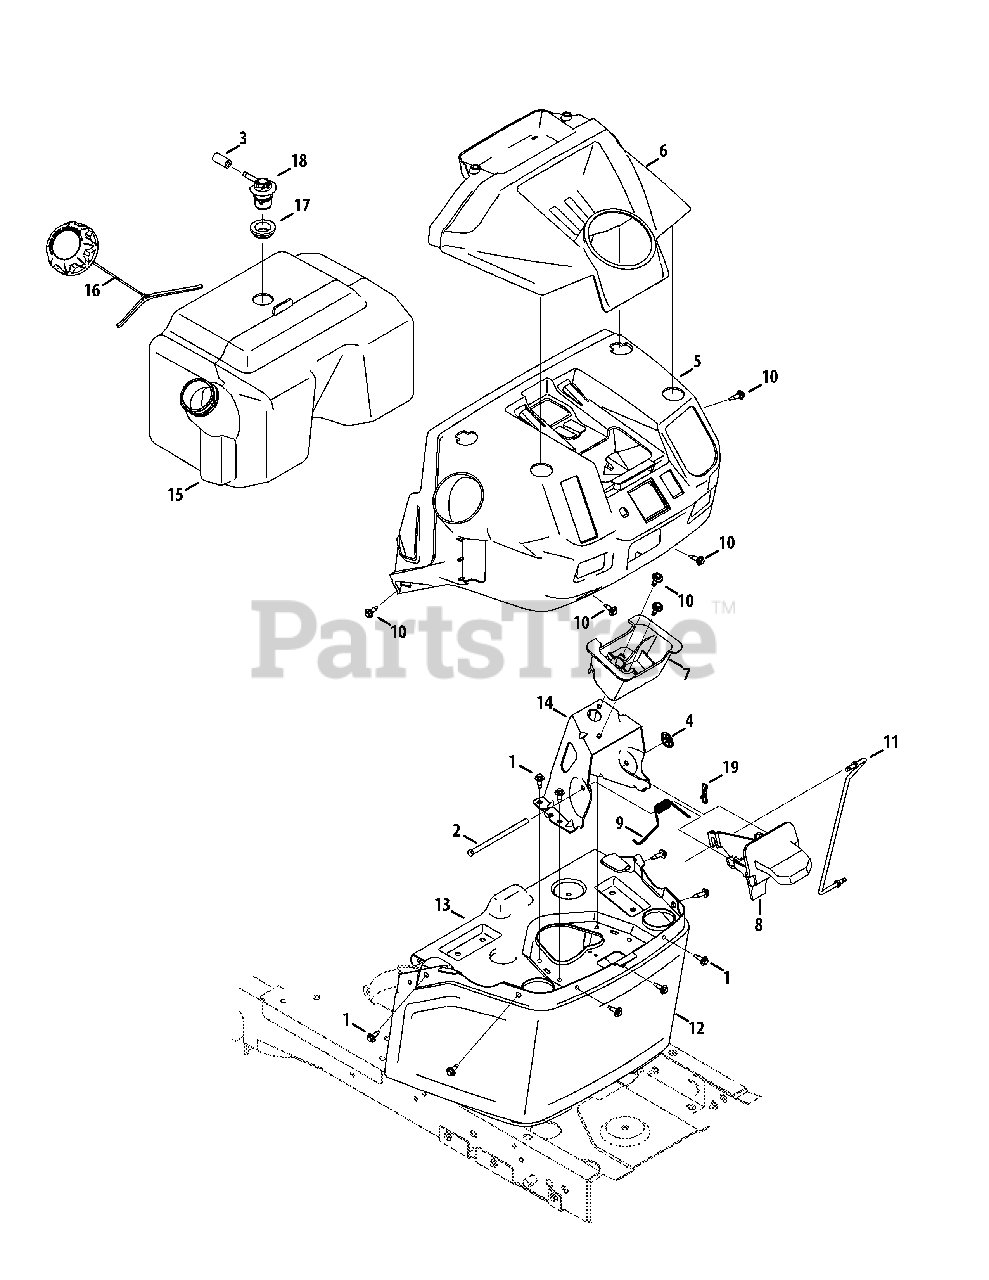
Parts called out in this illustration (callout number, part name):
1	Screw, M6-1 x .625
2	Hinge Pin, .25 Dia x 4.50 LG
3	Hose, Vent (Kohler Courage Single)
4	Push Nut, .25 Dia.
5	Upper Dash
6	Dash Cap
7	Steering Shaft Bearing
8	Dash Lever
9	Torsion Spring, .330 ID
10	Shoulder Screw, .368 x .115, M6-1
11	Control Rod
12	Lower Dash
13	Dash Plate
14	Steering Bearing Mounting Bracket
15	Tank, Fuel, 3 Gal.
16	Fuel Cap
17	Grommet, Rubber, 23.0 ID
18	Valve, Rollover Grommet
19	Pin, Cotter, Bow-Tie 72
